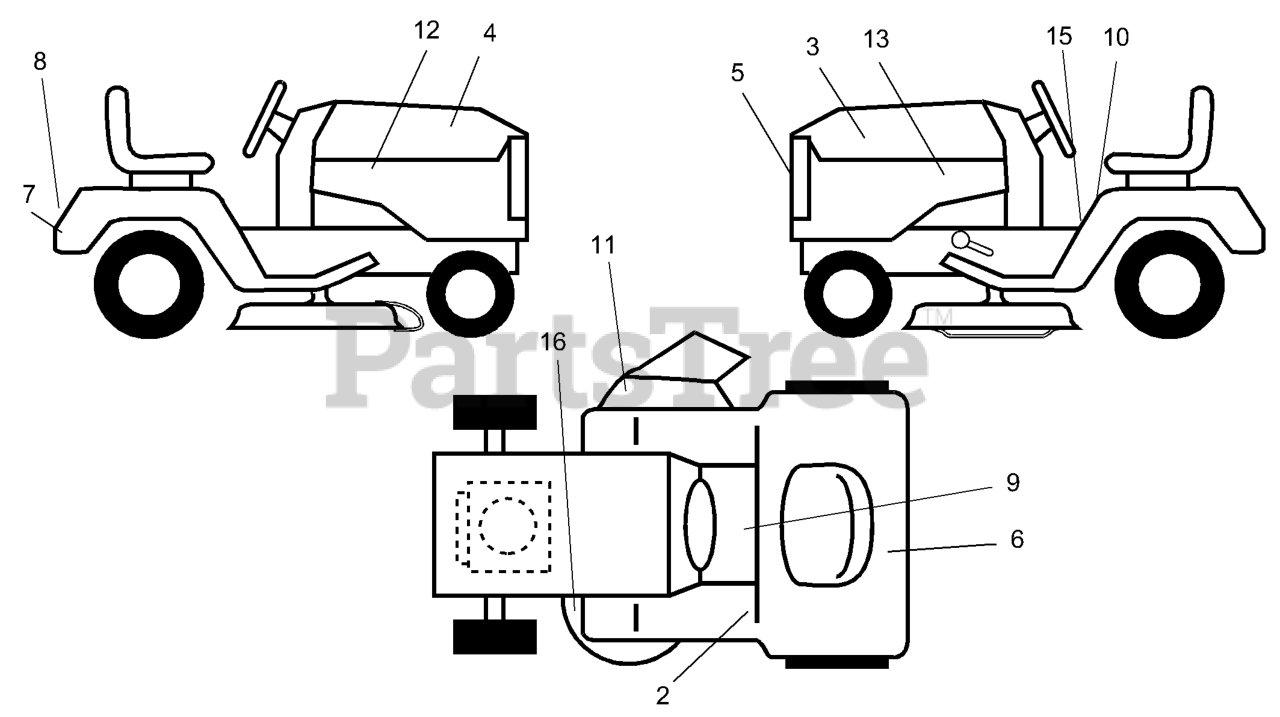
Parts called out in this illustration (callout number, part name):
2	IND HGT DECK DECAL
3	HOOD DECAL LH
4	HOOD DECAL RH
5	DECAL-GRILL
6	DECAL BTRY SYMBOLS
8	DECAL FENDER NLA
10	DECAL CAUTION
11	DECAL WARNING (ENGLISH/FRENCH)
15	DECAL OPER INSTRUCTION
16	DECAL V-BELT SCHEMATIC
